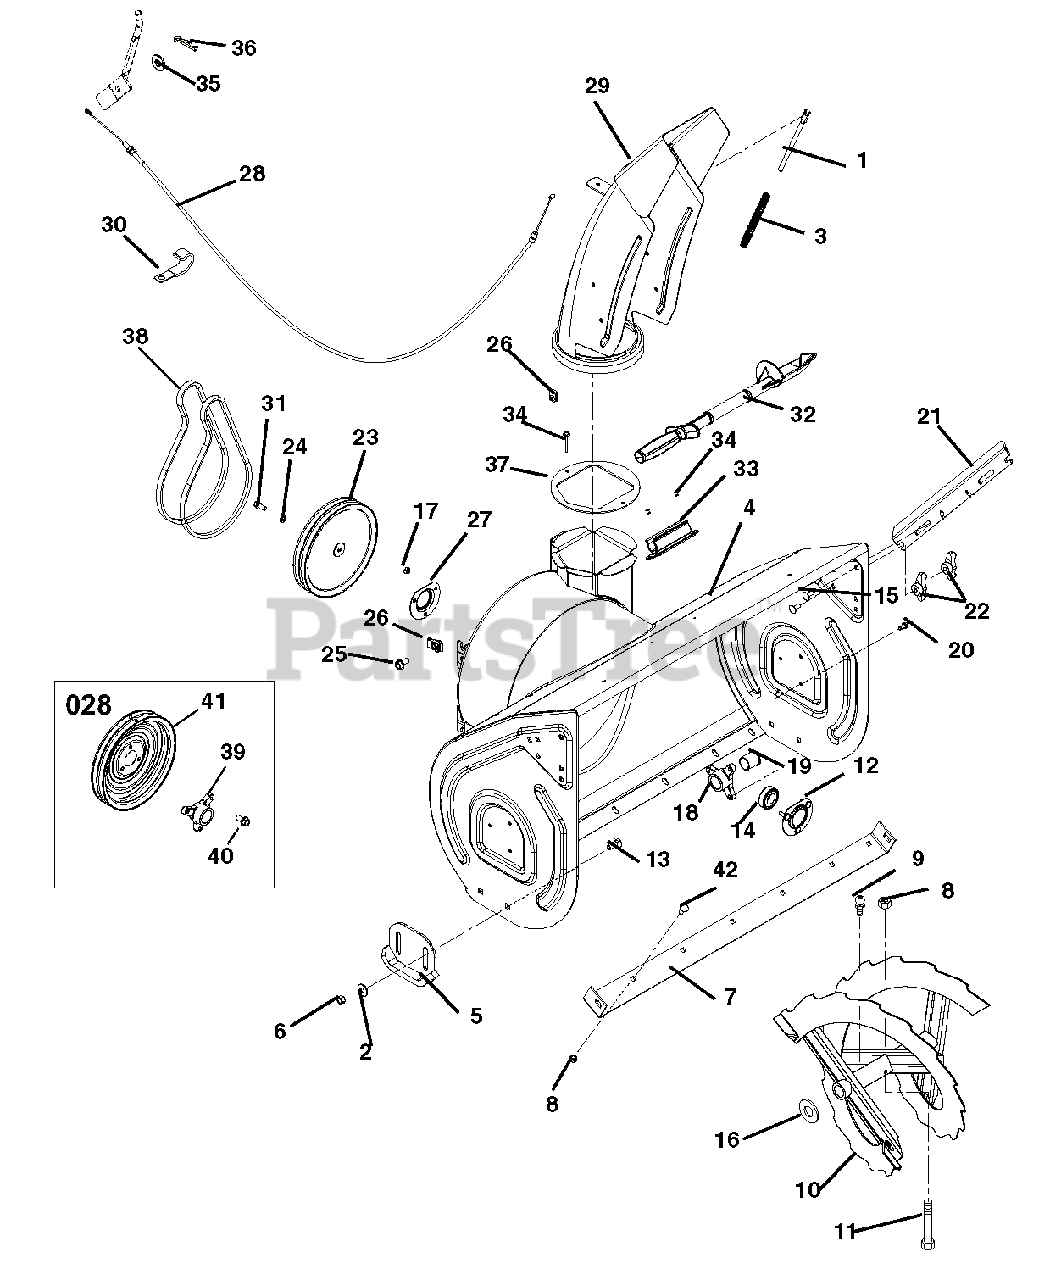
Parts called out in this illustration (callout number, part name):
1	ROD, DEFLECTOR CAP
2	@WSHR-FL-STL.438X1.00X.083 YWZ
3	SG-COMP .08X.40X6.50 14#/IN
4	HOUSING, BLOWER-26" W/DECAL
4	HOUSING, BLOWER-28" W/DECAL
4	HOUSING, BLOWER-32" W/DECAL
5	RUNNER, SKID SHOE-1/2" FLANGE
6	@NUT-LK-CTR .38-16 YWZC
7	BLADE, SCRAPER-26"
7	BLADE, SCRAPER-28"
7	BLADE, SCRAPER-32"
8	SKID SHOE, REVERSIBLE - ORANGE
8	@NUT-LK-TOP-FLG .31-18 YWZC
9	FTG-LUBE .25-28X.256 YWZC
10	RAKE, LH-26"(1 ID X 15.75 OD)
10	RAKE, RH-26" (1 ID X 15.75 OD)
10	RAKE, LH-28" (1 ID X 15.75 OD)
10	RAKE, RH-28" (1 ID X 15.75 OD)
10	RAKE, LH-32" (1 ID X 15.75 OD)
10	RAKE, RH-32" (1 ID X 15.75 OD)
10	RAKE, LH-32"(1 ID X 15.75 OD)
10	RAKE, RH-32"(1 ID X 15.75 OD)
11	SHEAR BOLT SERVICE ASSEMBLY
12	BEARING FLANGE
13	@BLT-RDHDSHSQNK.38-16X1.0 G5YZ
14	BRG-BALL .876 X 1.750 X .50
15	@BLT-RHDSSQNK .31-18X.75 G5YZ
16	WSHR-FL-STL 1.010X1.505X.062YZ
17	@NUT-LK-CTR .25-20 YWZC
18	BUSHING, RAKE SHAFT 1"
19	BSHG-FLG, SPLIT NYLINER 1.0"ID
20	SCR-TAP .25-20X.50 HWH TR YWZ
21	CUTTER, DRIFT
22	KNOB-CLAMPING, .312-18 NYLOC
23	PULLEY,2X4LX8.5 BOLTED
24	WSHR-LK .312X.097 HVY YWZC
25	BLT-SERHFWH .38-16X.75 YWZC
26	NUT-RTNR .375-16X.37
27	BEARING FLANGE
28	CABLE, DEFLECTOR
29	CHUTE, DISCHARGE-W/DEFLECTOR
30	J-CLAMP
31	BLT-HEX .31-24X.75 YWZC GR5
32	DEVICE, SNOW CLEAN OUT
33	MOUNT, SNOW CLEAN OUT
34	RVT-POP .187 YZ
35	@WSHR-FL-STL.281X.62X.065 YWZC
36	PIN-HAIR INT .06X.18X.77
37	BAFFLE, DISCHARGE NECK
38	V-BELT, HA-RAW EDGE (SET)
39	PULLEY HUB, BOLT-ON D-BORE .87
40	@SCR-TAP .31-18X.50 HWH TR YWZ
41	PULLEY, SPIN FORM DUAL GROOVE
42	@BLT-RHDSSQNK .31-18X.62 G5YZ
